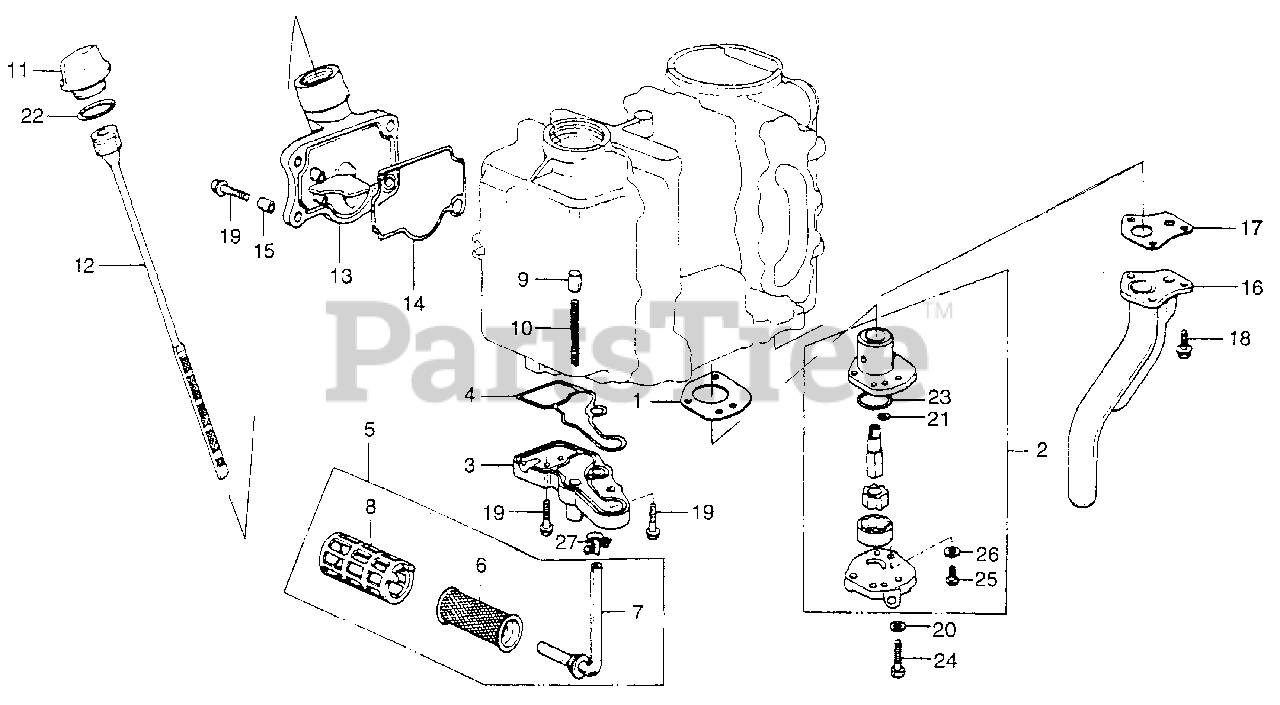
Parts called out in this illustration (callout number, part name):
1	GASKET, PUMP BODY
2	PUMP ASSY., OIL
3	FLANGE, OIL FILTER
4	GASKET, OIL FILTER
5	FILTER ASSY., OIL (NOT AVAILABLE)
6	FILTER, OIL
7	TUBE, OIL (NOT AVAILABLE)
8	HOLDER, OIL FILTER
9	VALVE, CHECK
10	SPRING, VALVE
11	CAP, OIL
12	DIPSTICK, OIL
13	BODY, OIL FILLER
14	GASKET, OIL FILLER BODY
15	COLLAR A, DISTANCE
16	PIPE, EX.
17	GASKET, EX. PIPE
18	BOLT, FLANGE (6X16)
19	BOLT, FLANGE (6X22)
20	WASHER A (6MM)
21	O-RING (6.8X1.9)
22	O-RING (26X2.7)
23	O-RING (25X1.0)
24	BOLT, HEX. (6X28)
25	SCREW, PAN (5X10)
26	WASHER, PLAIN (5MM)
27	CLIP, TUBE (A12)
